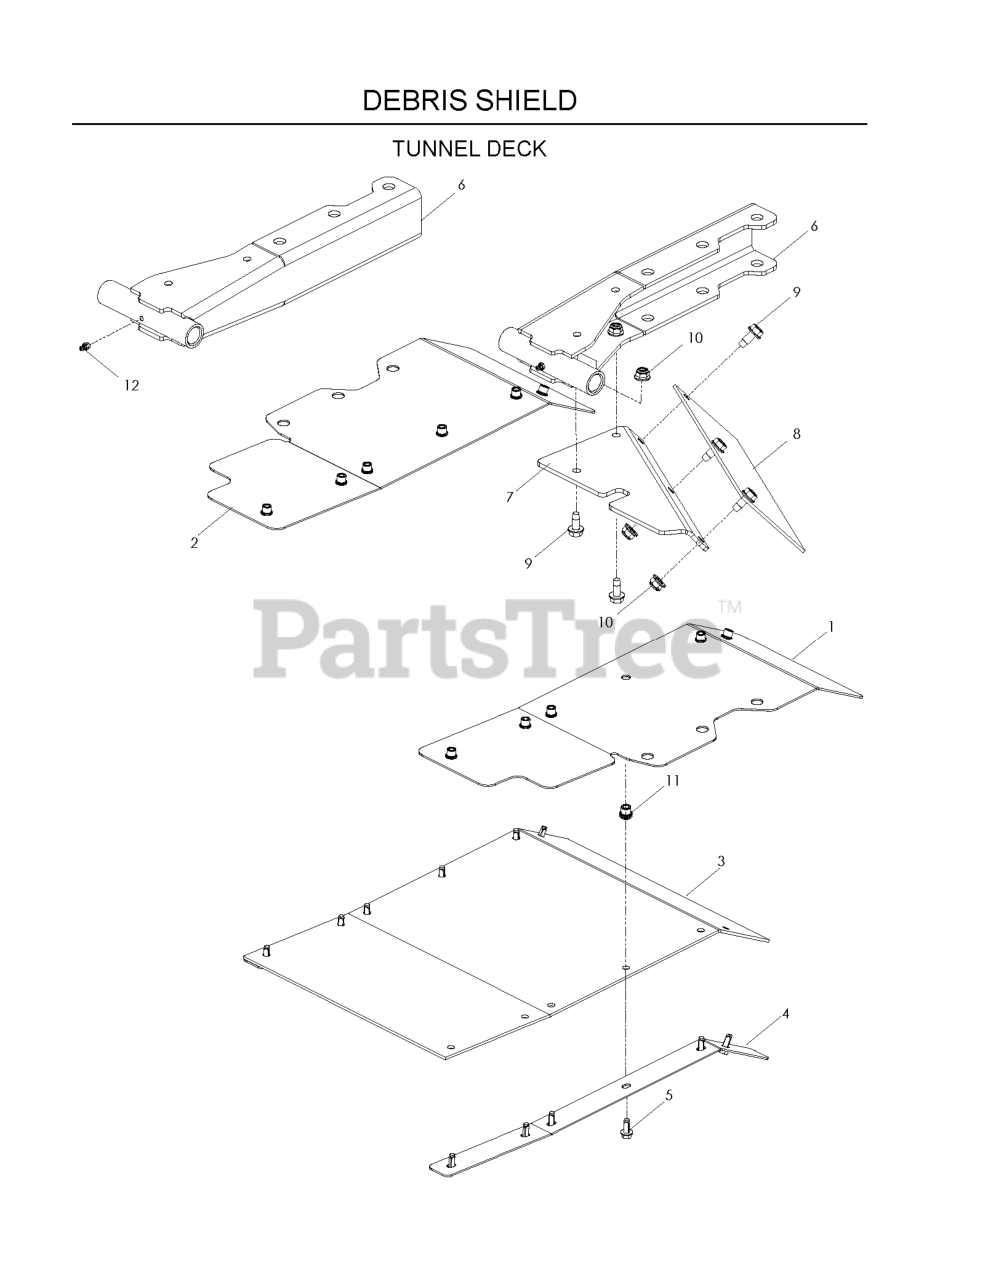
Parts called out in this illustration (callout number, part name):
1	GUARD, DEBRIS, LT, BLK
2	GUARD, DEBRIS, RT, BLK
3	GUARD, RUBBER
4	STRAP, GUARD, BLK
5	SCREW- 1/4-20 X 5/8
6	STRUT CMB BLK
8	GUARD, RUBBER, SMALL
9	BOLT 5/16-18 X 3/4
10	5/16-18 NYLOC FLANGE NUT
11	KNURLED INSERT
12	ZERK
